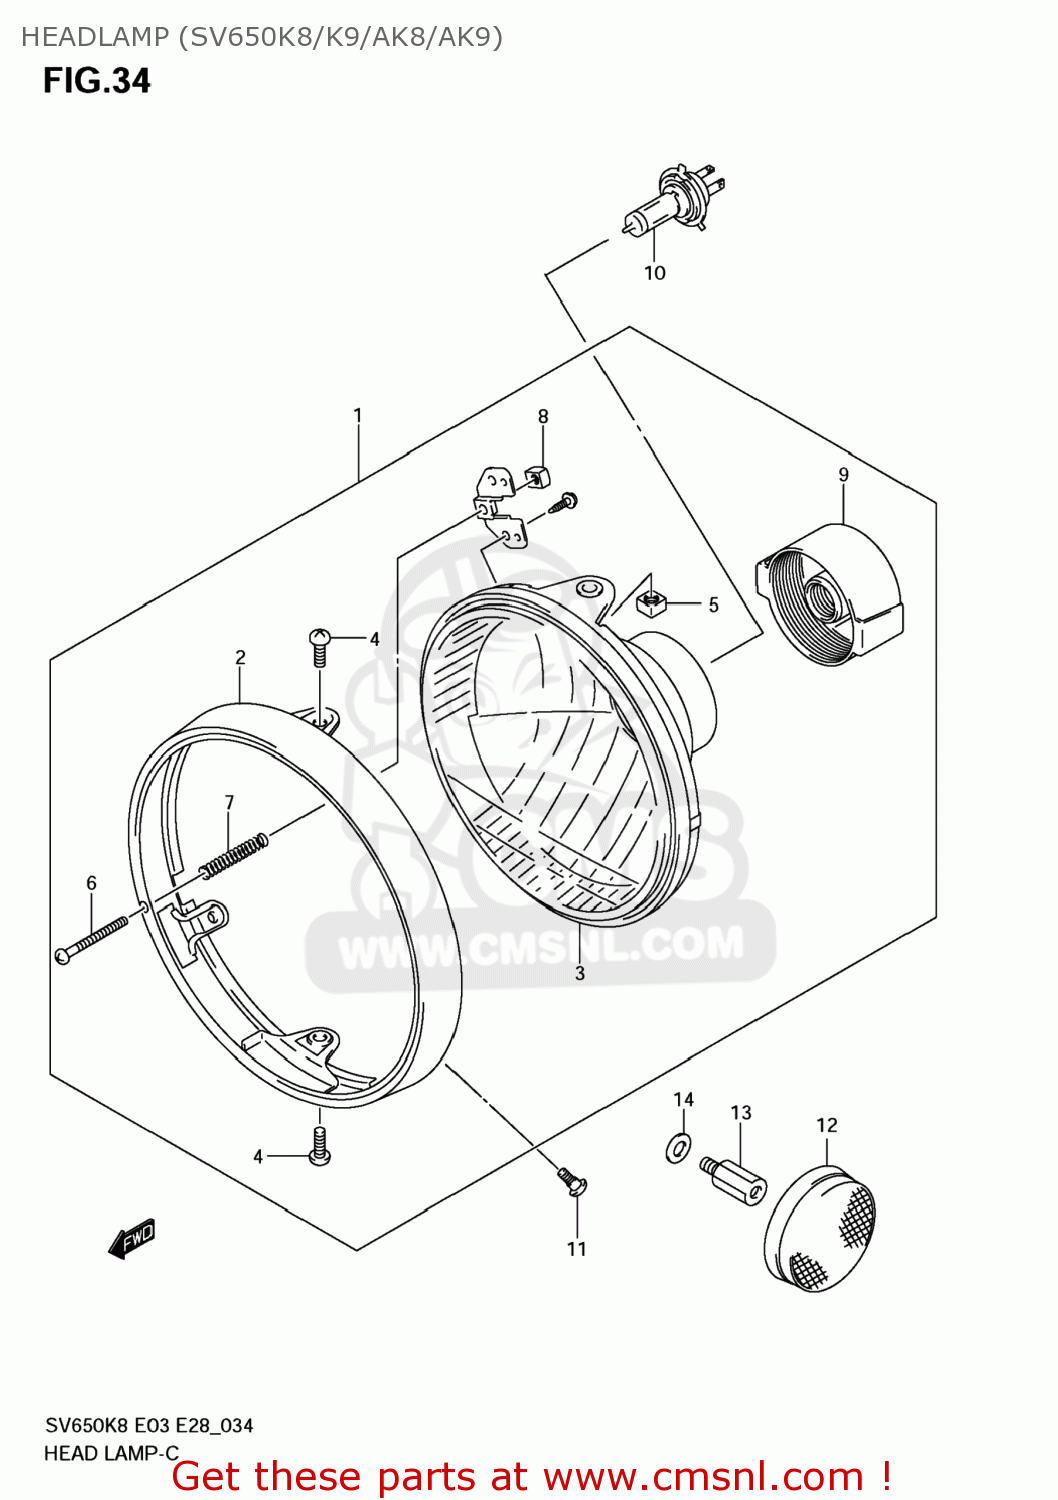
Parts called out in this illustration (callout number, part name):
1	HEADLAMP ASSY
2	RIM
3	LAMP UNIT
4	SCREW(5X16)
5	NUT
6	SCREW,ADJUSTING
7	SPRING
8	NUT,HEADLAMP ADJUST
9	COVER,SOCKET
10	BULB(12V60/55W,H4)
11	SCREW(5X15.3)
12	REFLECTOR,REFLEX
13	BOLT(5X10)
14	WASHER
